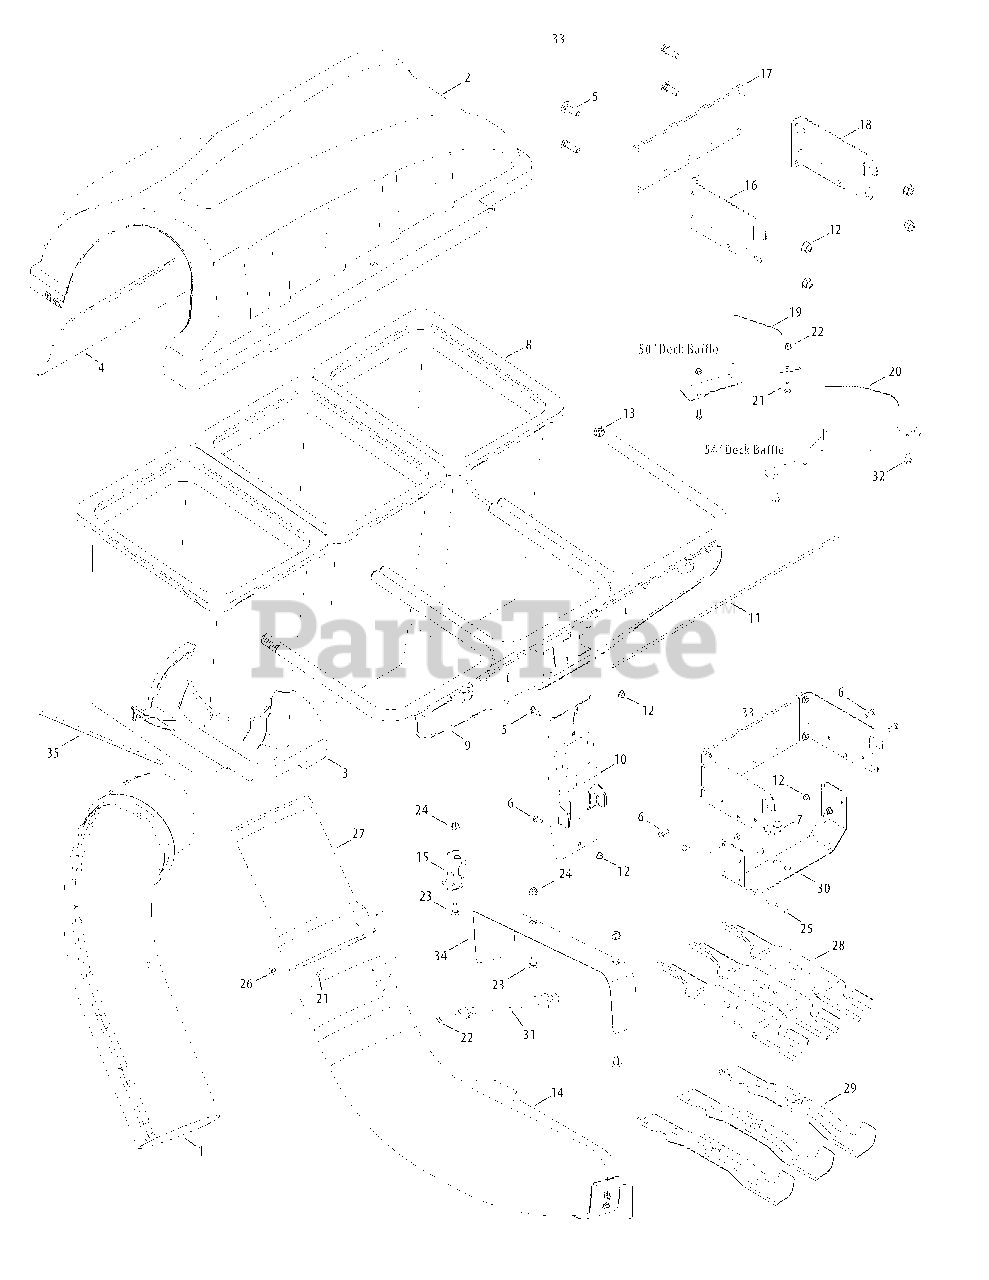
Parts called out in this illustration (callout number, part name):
1	Upper Chute Assembly
2	Triple Bagger Cover Assembly
3	Upper Chute Support
4	Bagger Cover Screen
5	Carriage Screw, 5/16-18 x 1.00"
6	Hex Head Screw, 5/16-18 x .75"
7	Clevis Pin, .62" Dia.
8	Grass-bag Assembly
11	Cover Hinge Pin
12	Flange Lock Nut, 5/16-18
14	Discharge Chute Elbow, 50/54" Deck
15	Chute Stop-Bracket
16	Hitch Bracket, RH
17	Universal Rear Attachment Bracket
18	Hitch Bracket, LH
19	Deck Baffle, 50"
20	Deck Baffle, 54"
21	Tap Screw, 1/4 - 20 x .750 (50" Deck)
22	Flange Lock Nut, 1/4 - 20 (50" Deck)
23	Carriage Screw, 3/8 - 16 x 1.00"
24	Flange Lock Nut, 3/8 - 16
25	Internal Cotter Pin, .148 x 3.00
26	Ratchet Clip, .250
27	Bagger Chute Adapter, 7 In.
28	Blade, 18.50 Lg., High Lift
29	Blade, 17.90 Lg., Star Bagging
30	Universal Bracket Support
31	Chute Strap
32	Tap Screw, 5/16-18 x .750 (54" Deck)
33	Mounting Bracket Kit (Incl. Ref. 16-18)
35	Adhesive Foam Strip
